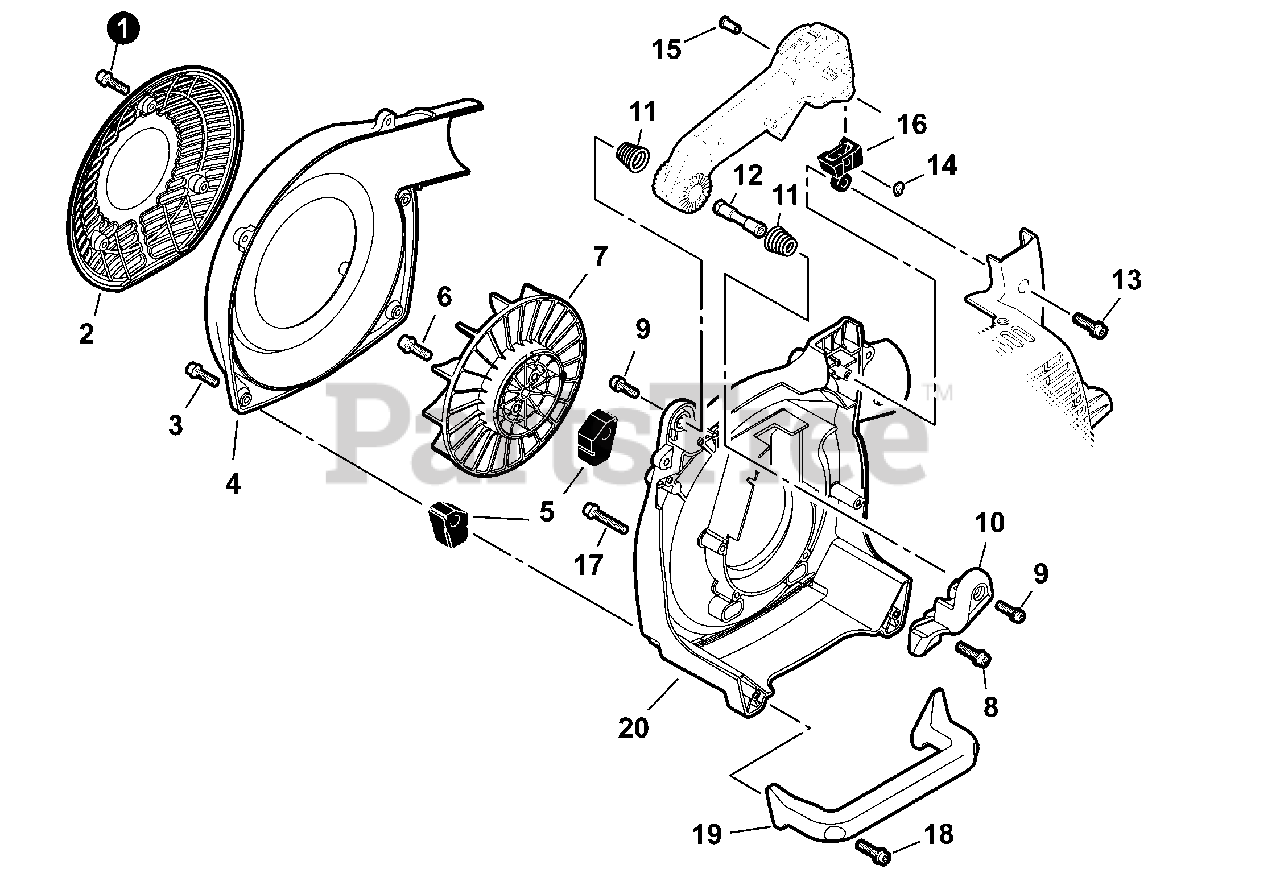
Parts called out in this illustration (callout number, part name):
1	BOLT M5×20
2	COVER, INTAKE
3	BOLT M5×20
4	COVER, FAN
5	CUSHION
6	BOLT M6×20
7	FAN Ø185
8	BOLT M5×20
9	SCREW, ADHESIVE M5×16
10	MOUNT, HANDLE
11	SPRING, COIL Ø18ר14
12	NUT, HANDLE 5
13	BOLT M5×20
14	RING, SNAP 8 MM
15	PIN, LOCK
16	CUSHION, AV
17	BOLT M5×40
18	BOLT M5×20
19	HANDLE, SIDE
20	CASE, FAN
